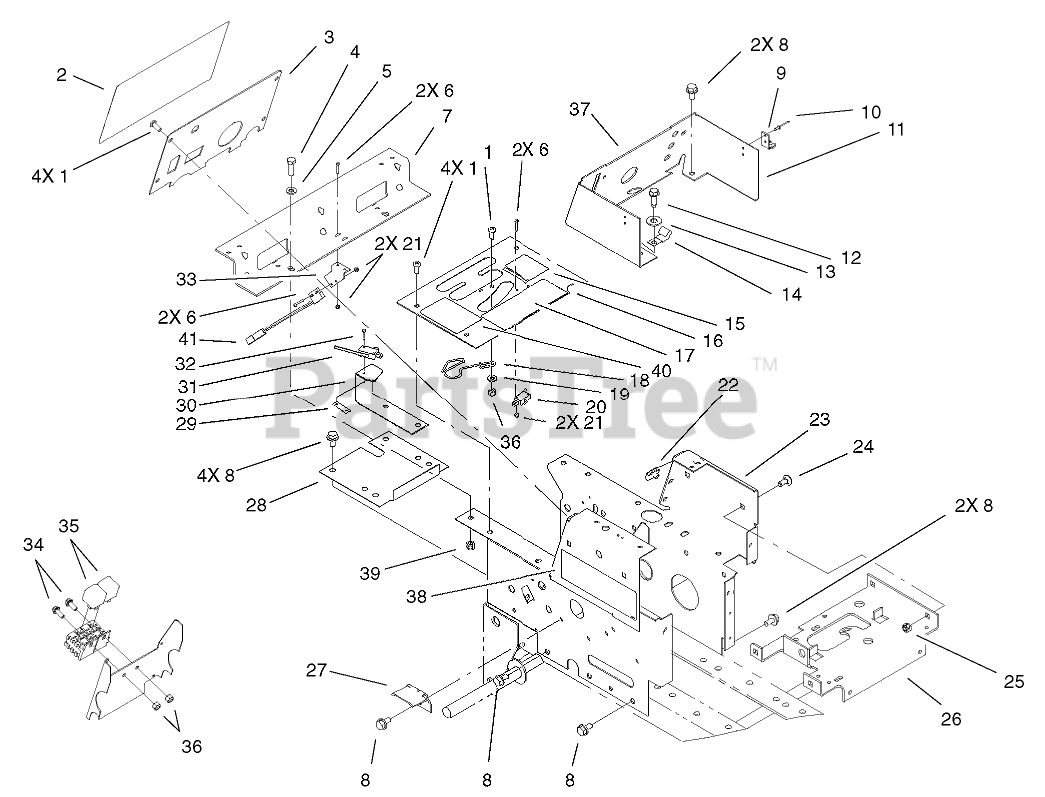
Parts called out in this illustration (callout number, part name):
1	SCREW-PPH
2	DECAL-DASH, LOWER
3	PLATE-HOODSTAND
4	SCREW-HH
5	WASHER-PLAIN
6	SCREW-PPH
7	BRACKET-FENDER
8	SCREW-HWHTF
9	KEEPER-LATCH
10	RIVET-POP
11	CONSOLE
12	SCREW-TAPTITE
13	WASHER-FLAT
14	J-CLIP
15	DECAL-PARKING, BRAKE
16	PLATE-SHIFT
17	DECAL-DANGER
18	SPRING-SHIFT CONTROL
19	WASHER-FLAT
20	SWITCH
21	NUT-HEX
23	HOODSTAND ASM
24	BOLT-CARR
25	NUT-LOCK, NI
26	SUPPORT-BATTERY
27	BRACKET-BELT SUPPORT
28	COVER-DUST
29	NUT-SPEED
30	BRACKET-SWITCH, REVERSE
31	SWITCH-MICRO
32	SCREW-HH
33	BRACKET-SWITCH, REED
34	SCREW-HHF
35	RELAY
36	NUT-LOCK, NI
37	DECAL-CONSOLE
38	DECAL-MODEL 315-8
39	NUT-LOCK, NI
40	DECAL-SHIFT PATTERN
41	SWITCH-REED, MAGNETIC
